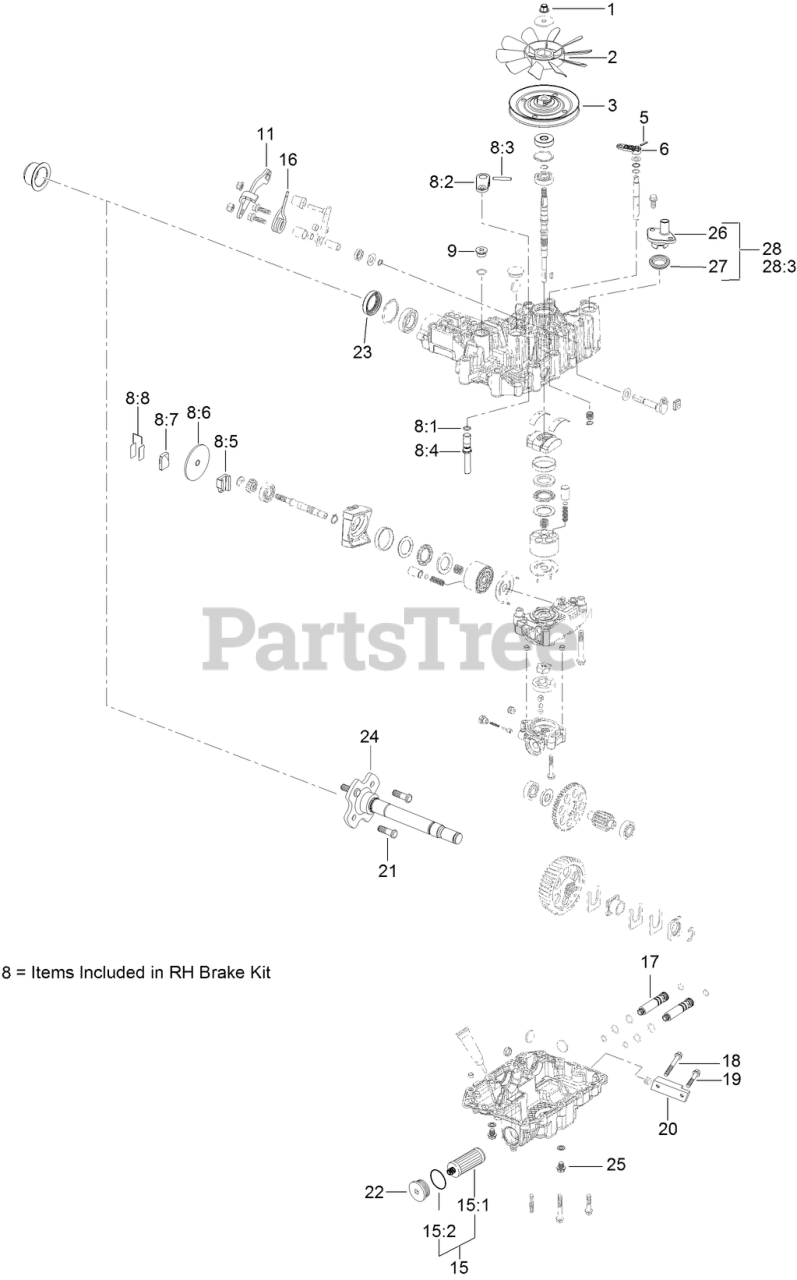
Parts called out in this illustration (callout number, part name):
1	NUT-LOCK
3	PULLEY
6	LEVER-BYPASS
8	BRAKE KIT,LEFT
8:1	O-RING
8:2	ARM-BRAKE
8:3	Pin-Roll
8:4	SHAFT-BRAKE
8:5	ACTUATOR-BRAKE
8:6	DISC-BRAKE
8:7	SHOE-BRAKE
8:8	SHIM KIT
9	CAP-OIL
11	LEVER-CONTROL, RH
15	HYDRO FILTER KIT
15:1	FILTER
15:2	O-RING
16	SPRING-TORSION
17	CONNECTOR
19	SCREW-HHF
20	MANIFOLD
21	STUD-WHEEL
22	CAP-OIL FILTER
23	SEAL-AXLE, UA
25	DRAIN BOLT
26	EXPANSION FITTING
27	GROMMET SEAL, EXPANSION FITTING
28	EXPANSION FITTING - W/ SEAL
28:3	M8*20 FLANGE BOLT
